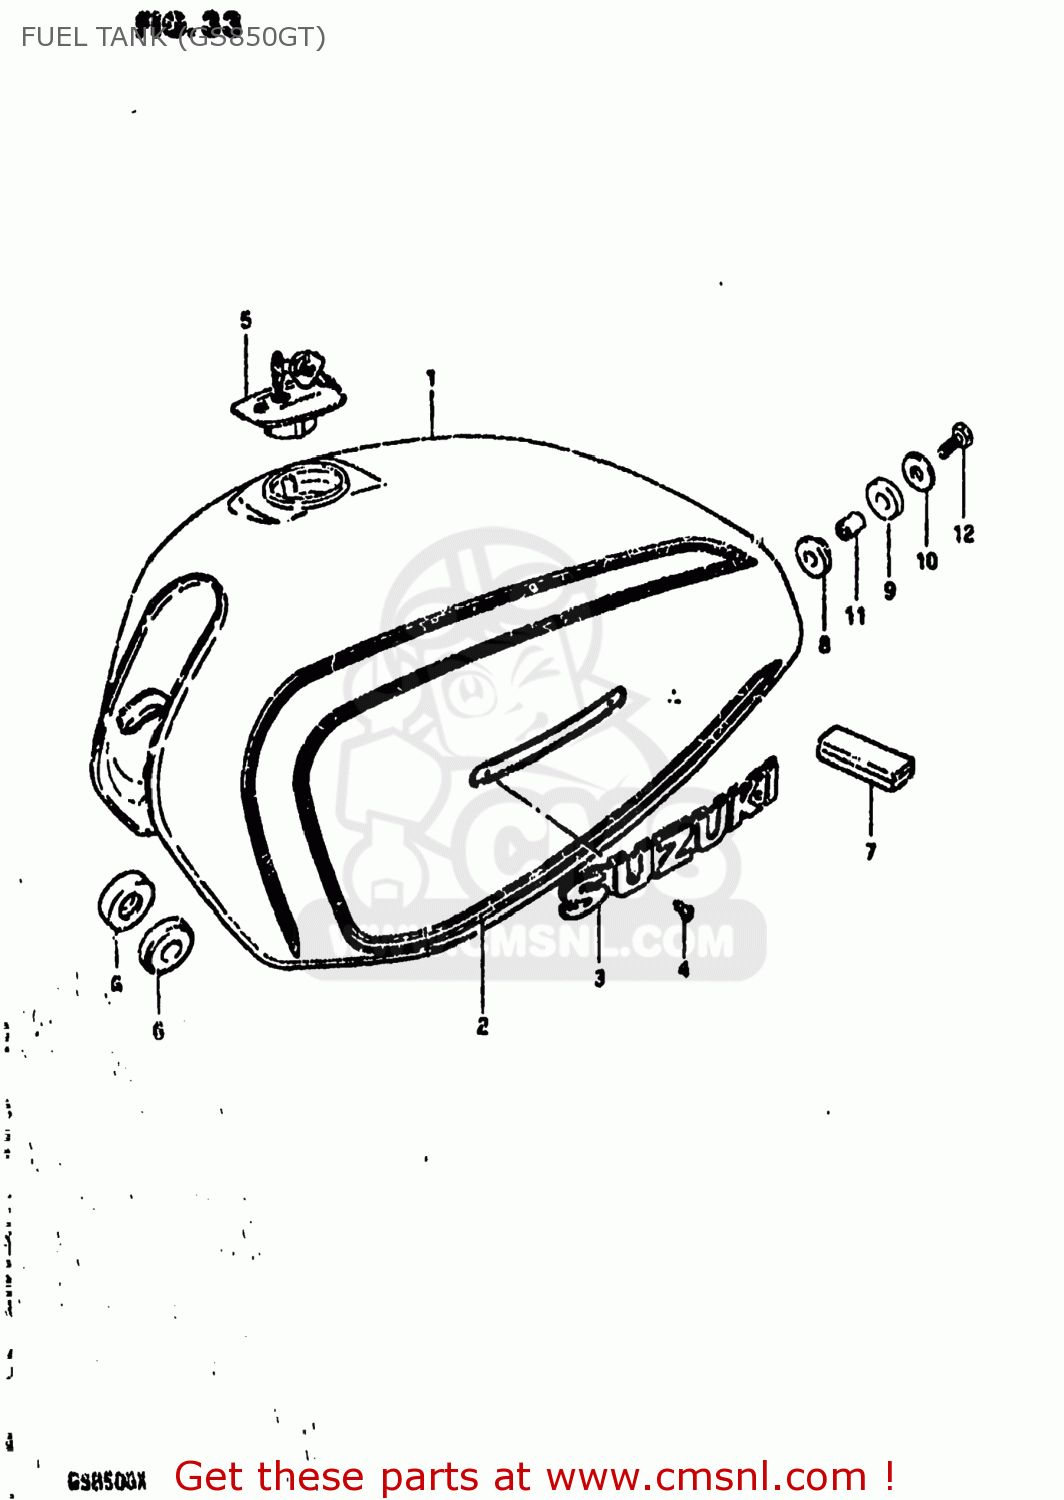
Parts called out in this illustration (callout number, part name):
1	TANK ASSEMBLY,FUEL
2	TAPE SET,FUEL TANK
3	EMBLEM,FUEL TANK
4	SCREW 3X6
5	CAP SET,FUEL TANK
6	CUSHION
7	CUSHION
8	CUSHION
9	CUSHION
10	WASHER (8.5X29X1.6)
11	SPACER(8.5X12X19)
12	BOLT (8X30)
